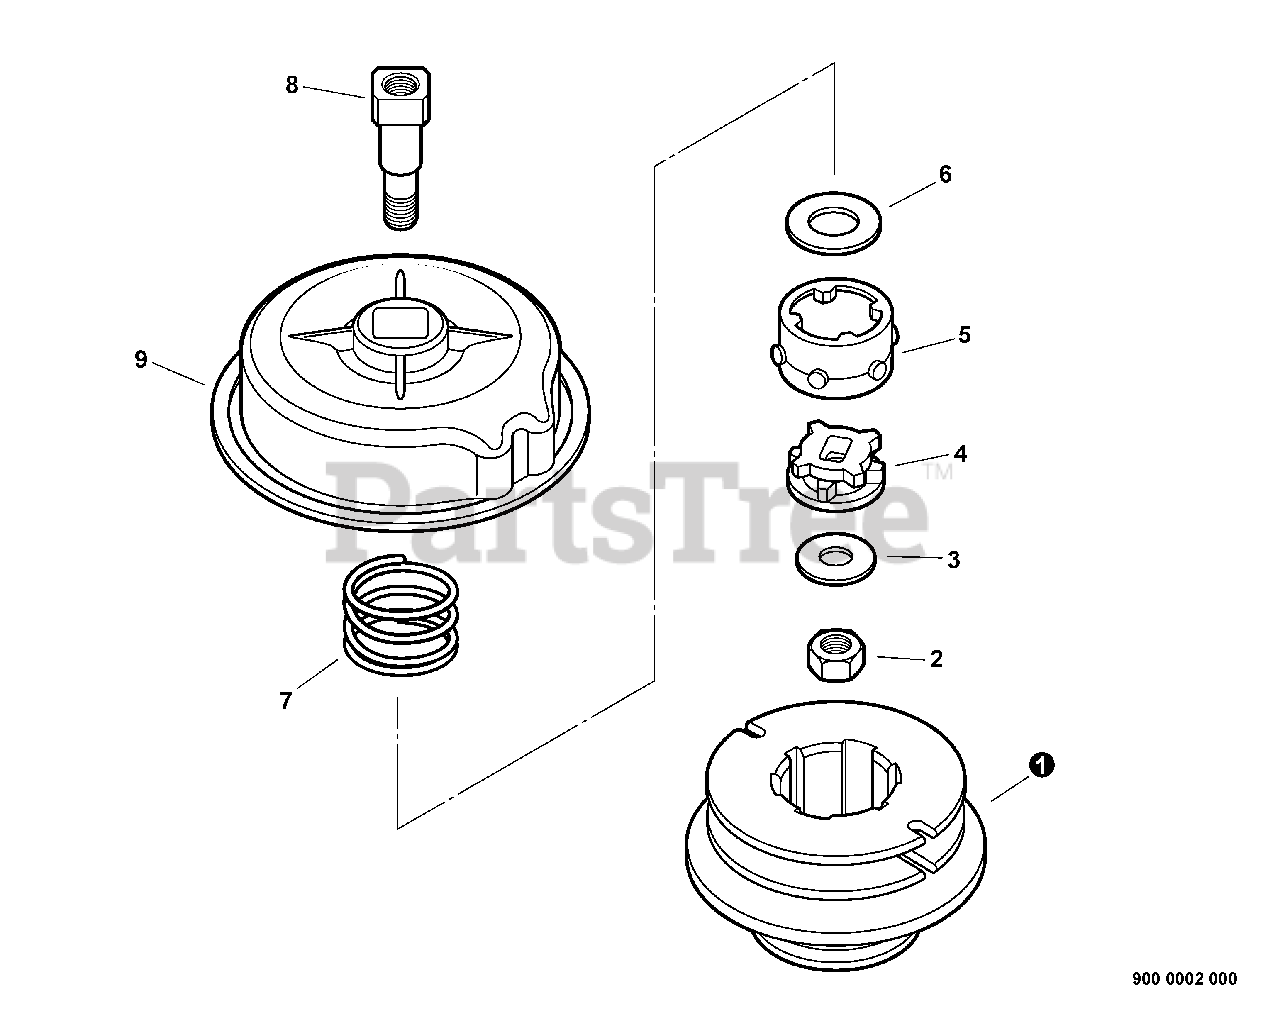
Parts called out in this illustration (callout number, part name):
2	LOCKNUT
4	CAM - INNER
5	DRIVER, OUTER
8	BOLT, SHAFT - 10
9	HOUSING
